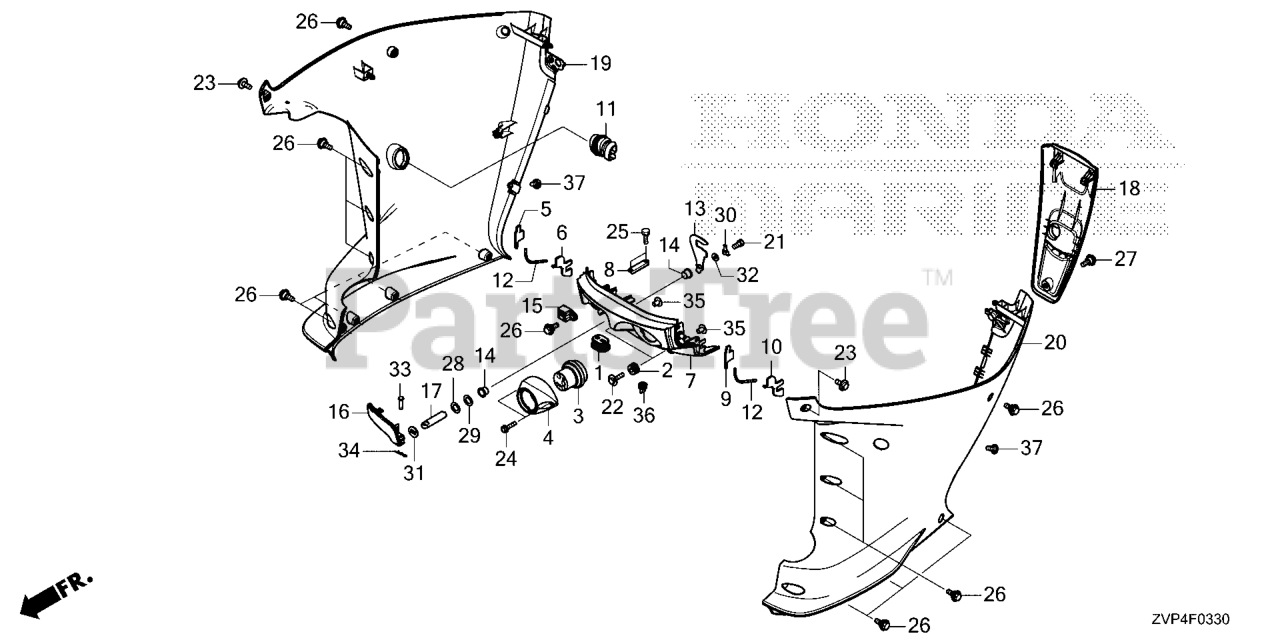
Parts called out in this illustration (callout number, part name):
1	GROMMET, SENSOR HARN
2	GROMMET, CASE (LOWER)
3	GROM, CASE (LOWER)
4	COVER, SEPARATE
5	SEAL, FR. BRACKET R
6	SEAL, FR. BRACKET R
7	BRACKET, FR. *NH565*
7	BRKT, FR. *NHB14M*
8	STAY, FR. BRACKET
9	SEAL, FR. BRACKET L
10	SEAL, FR. BRACKET L
11	RUBBER, DRAIN PLUG
12	SEAL, MID COVER F
13	HOOK, FR. COVER LOCK
14	BUSH, COVER LOCK
15	HOLDER, LOCK LEVER
16	LEVER, FR. *NH565*
16	LEVER, FR. *NHB14M*
17	SHAFT COVER LOCK
18	COVER, RR. *NH547*
19	COVER COMP *NH565*
19	COVER COMP *NHB14M*
20	COVER COMP *NH565*
20	COVER COMP *NHB14M*
21	BOLT, HEX. (6X12) Use up to Frame SN 1005248.
22	BOLT-WASHER (6X27)
23	BOLT-WASHER (6X16)
24	BOLT, FLANGE (6X25)
25	BOLT, HEX. (6X14)
26	BOLT, SPECIAL (6X17)
27	BOLT, SPECIAL (6X17)
28	WASHER, PLAIN RUBBER
29	WASHER (14MM)
30	WASHER, LOCK
31	WASHER, PIVOT
32	WASHER, PLAIN (6MM)
33	PIN (5X17.8)
34	PIN, LOCK (5MM)
35	COLLAR (12X6.5)
36	GROMMET (1WAY)
37	SCREW, PAN (6X14)
